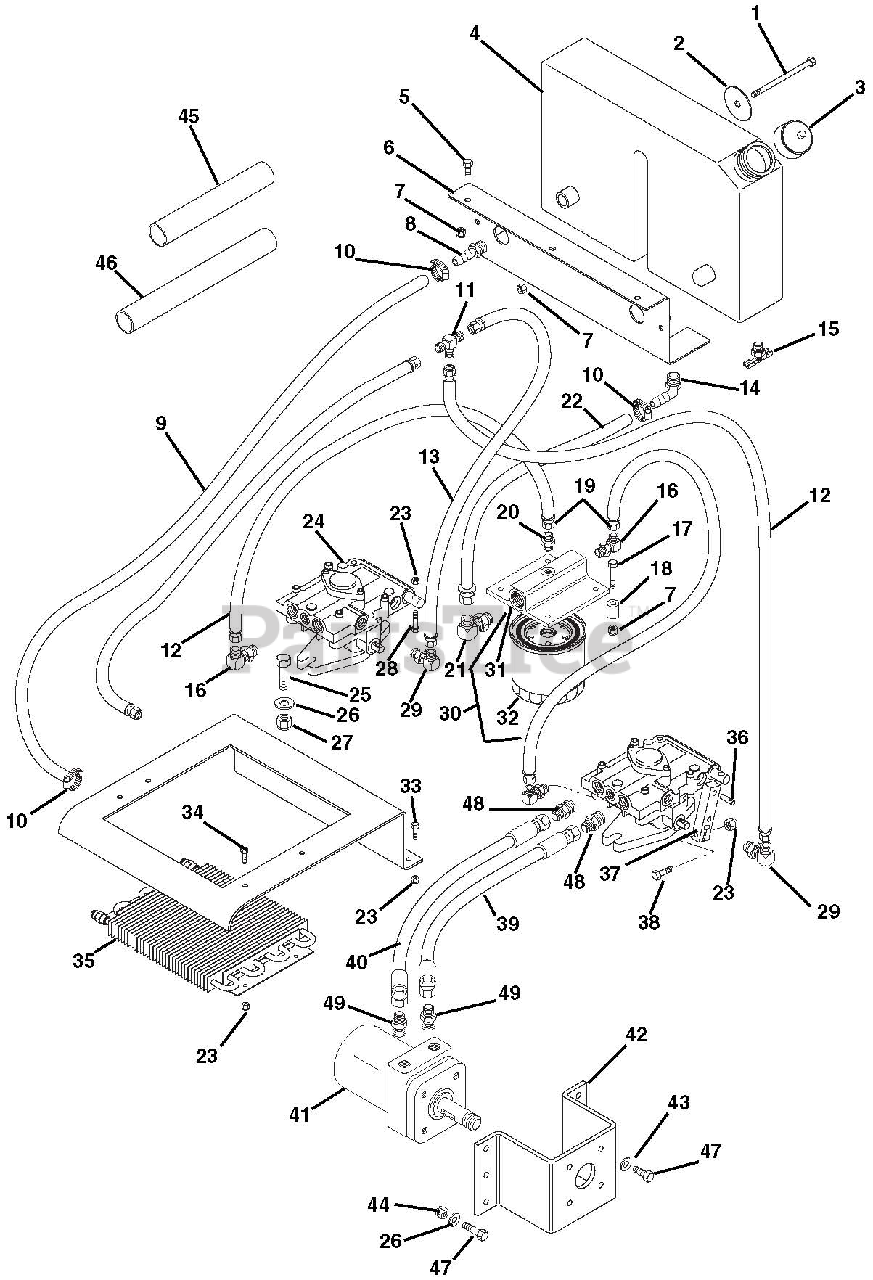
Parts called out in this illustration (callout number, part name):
1	Bolt-Hex .31-18 x 3.50 Grade 5
2	Washer-Flat .344 x 3.00 x .06
3	Cap, Tank
4	Tank, Hydraulic
5	Bolt-Hex .31-18 x .75 Grade 5
6	Bracket-Hydraulic Tank Mounting
7	Nut-Locking-Center .31-18
8	Adapter-Male
9	Hose-Oil Cooler To Tank
10	Clamp, .88 Diameter Hose
11	Adapter Tee .56-18
12	Hose-Hydraulic Valve To Tank
13	Hose-Pump to Tee
14	Fitting-Elbow .50 x .50
15	Drain-cock .38 x .69 x 1.25
16	Adapter 2503-4-4
17	Bolt-Hex. .31-18 x 2.00 Grade 5
18	Bushing-Split .328 x .462 x .75
19	Hose-Oil Filter to Pump
20	Adapter 0503-4-4
21	Adapter-Pipe .75-16
22	Hose-Tank to Oil Filter
23	Nut-Locking-Center .25-20
24	Variable Pump
25	Bolt-Hex .38-16 x 1.125
26	Washer-Flat-Steel .406 x .812 x .065
27	Nut-Locking-Center .38-16
28	Bolt-Hex .25-20 x 2.00 Grade 5
29	Adapter 2503-6-6
30	Assembly-Spin-On Lube
31	Assembly-Head
32	Element
33	Bracket-Oil Cooler
34	Bolt-Hex .25-20 x .75 Grade 5
35	Oil Cooler
36	Pin, Dowel .312 x 1.25
37	Arm, Pump Actuating
38	Bolt-Hex .25-20 x 1.25 Grade 5
39	Assembly-Hose-Wheel Motor to Pump-15.25
40	Assembly-Hose-Wheel Motor to Pump-17
41	Motor, Hydraulic Wheel
42	Bracket, Wheel Motor
43	Washer-Lock .375 x .094
44	Nut-Locking-Nylon .38-16
45	Sleeve 12 inch
46	Sleeve 18 inch
47	Bolt-Hex .38-16 x 1.25 Grade 5
48	Adapter, Face Seal 8 x 8 .50 O-Ring
49	Adapter, Face Seal 10 x 8 .625 O-Ring
